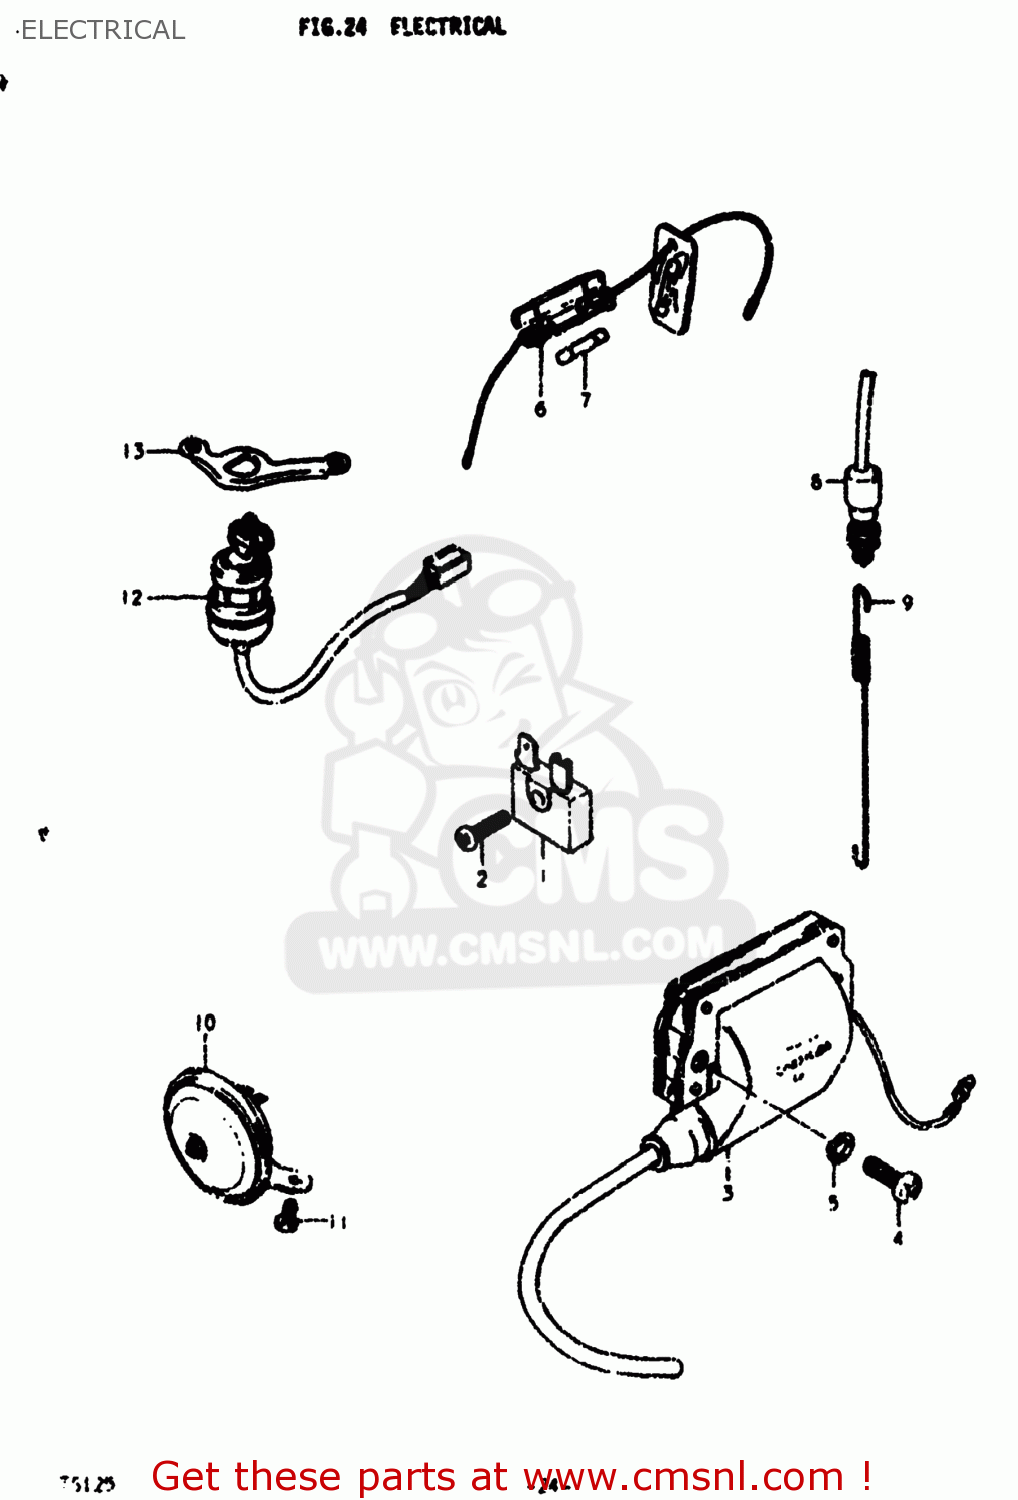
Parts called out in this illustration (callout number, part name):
1	RECTIFIER ASSEMBLY
2	SCREW
3	COIL ASSEMBLY,IGNITION
4	SCREW
5	LOCK WASHER
6	BOX ASSEMBLY,FUSE
7	FUSE(10A)
8	SWITCH ASSY, STOP LAMP
9	SPRING
10	HORN ASSEMBLY
11	BOLT
12	SWITCH ASSEMBLY,IGNITION
13	BRACKET,IGNITION SWITCH
